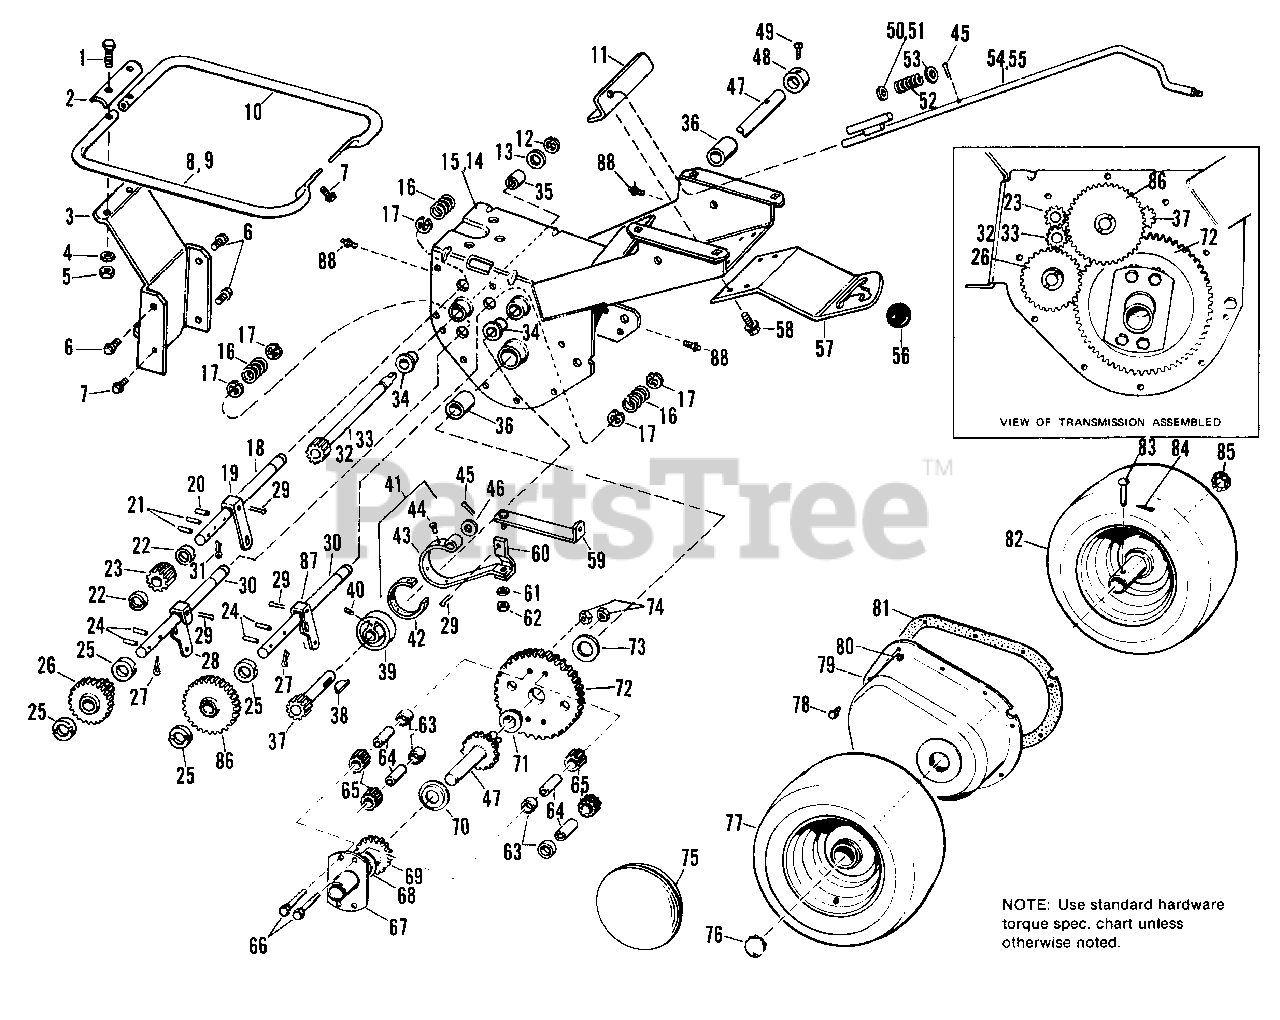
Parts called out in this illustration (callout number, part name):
1	CAPSCREW, Hex Hd., 5/16-18 x 1-1/2
2	BRACKET, Handle Support
3	PLATE, Hitch, Rear
4	LOCKWASHER, 5/16
5	NUT, Hex, Full, 5/16-18
6	SCREW, Hex, Taptite, 5/16-18 x 1/2
7	SCREW, Hex, Taptite, 1/4-20 x 1/2
8	HANDLE, Rear, R.H.
9	HANDLE, Rear, R.H.
10	HANDLE, Rear, L.H.
11	GUIDE, Shift rod
12	RING, Retaining
14	ENGINE BASE FRAME & SEAT SUPPORT ASSY.
15	ENGINE BASE FRAME & SEAT SUPPORT ASSY.
16	SPRING, Compression
17	RING, Retaining
18	SHAFT, Reverse
19	LINK, Shift, Reverse
20	PIN, Roll, 5/32 Dia. x 1
21	PIN, Roll, 1/8 Dia. x 3/4
22	COLLAR, Thrust
23	PINION, Reverse
24	PIN, Roll, 1/8 Dia. x 1
25	COLLAR, Thrust
26	GEAR & BEARING ASSY.
27	PIN, Cotter, 3/32 x 3/4
28	LINK, Shift, Hi
29	PIN, Cotter, 3/16 x 1-1/4
30	SHAFT, Intermediate
31	PIN. Cotter, 1/16 x 3/4
32	SHAFT ASSY., Gear
33	SHAFT ASSY., Gear
34	BEARING, Bronze
37	BRAKE SHAFT & GEAR ASSY.
38	KEY, Hi-Pro
39	DRUM, Brake
40	SETSCREW, 5/16-18 x 5/16
41	BAND ASSY., Brake
42	LINING, Brake
43	BAND, Brake
44	RIVET, #7 x 1/4
45	PIN, Cotter, 1/8 x 1
46	WASHER, Plain, 3/8
47	SHAFT ASSY., Axle, L.H.
48	COLLAR, Set
49	SETSCREW, 5/16-18 x 3/8
50	WASHER, Plain
51	WASHER, Spacer
53	WASHER, Plain, 7/16
54	CONVERSION KIT, Shift
55	ROD ASSY., Shift
56	KNOB, SHIFT
57	PLATE, Shift Pattern
58	SCREW, Taptite, 1/4-20 x 3/4
59	GUIDE ASSY., Brake
60	LEVER, Brake
61	LOCKWASHER, 1/4
62	NUT, Hex, Full, 1/4-20
63	SPACER, Diff.
64	SPINDLE, Differential Pinion
65	PINION, Diff.
66	CAPSCREW, Hex Hd., 3/8-16 x 2-3/4
67	PLATE, Diff.
68	BUSHING, Plate Diff.
69	AXLE & BUSHING ASSY., R.H.
70	CUP, Thrust
72	GEAR, Drive
74	LOCKNUT, Hex, 3/8-16
75	HUB CAP, Rear
76	BUTTON, Plug
77	WHEEL & TIRE ASSY., R.H.
78	SCREW, Hex, Taptite, 1/4-20 x 3/8
79	GEAR CASE ASSY.
80	FITTING, Grease
81	GASKET, Gear Case
82	WHEEL & TIRE ASSY., L.H.
83	PIN
84	PIN, Cotter, 1/8 x 3/4
85	BUTTON, Plug
86	GEAR & BEARING ASSY., Lo
87	LINK, Shift, Lo
88	FITTING, Grease
